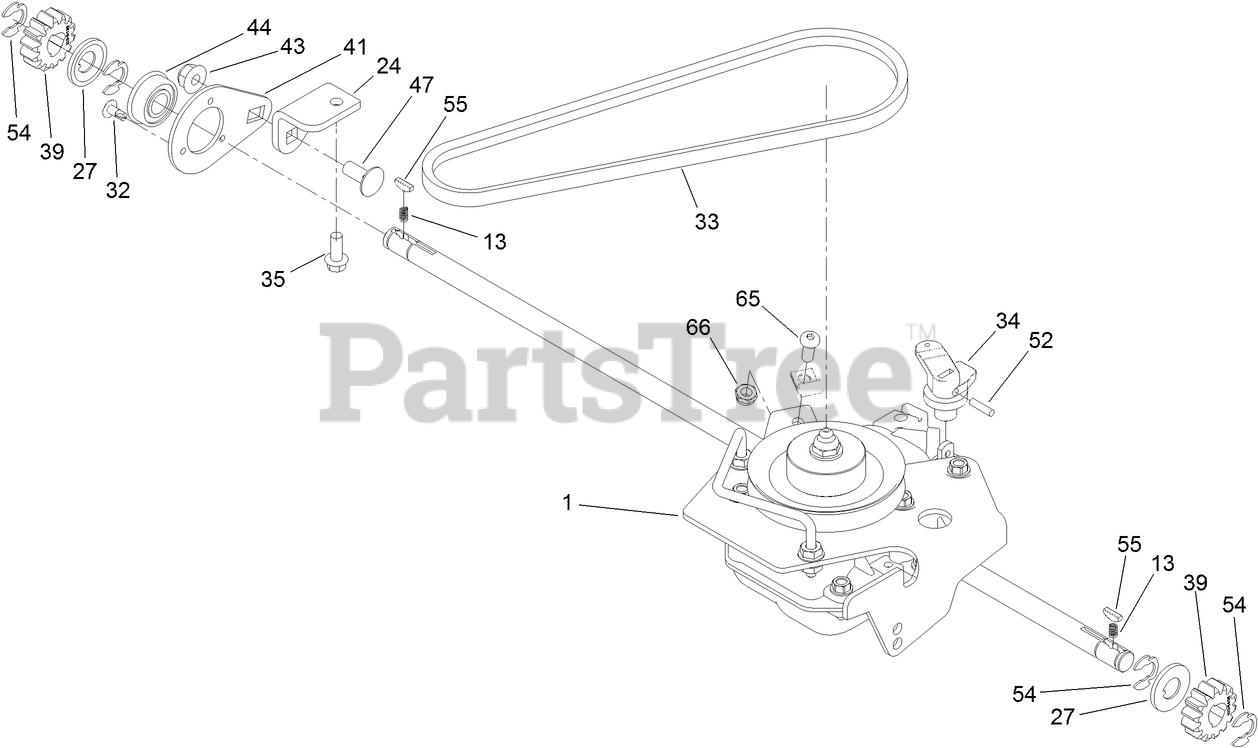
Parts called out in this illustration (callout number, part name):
1	GEAR CASE ASM
13	SPRING-COMPRESSION
24	BRACKET-BEARING, PLATED
27	WASHER-THRUST, OUTER
32	SCREW-TAP
33	BELT-V, TRACTION
34	LEVER-SHIFT
35	SCREW-HWH
39	GEAR-PINION
41	PLATE-BEARING
43	NUT-HF, NI
44	BEARING-BALL
47	SCREW-CARR
52	PIN-COIL
54	RING-RETAINING
65	SCREW-HSBH
66	NUT-LOCK, NI
